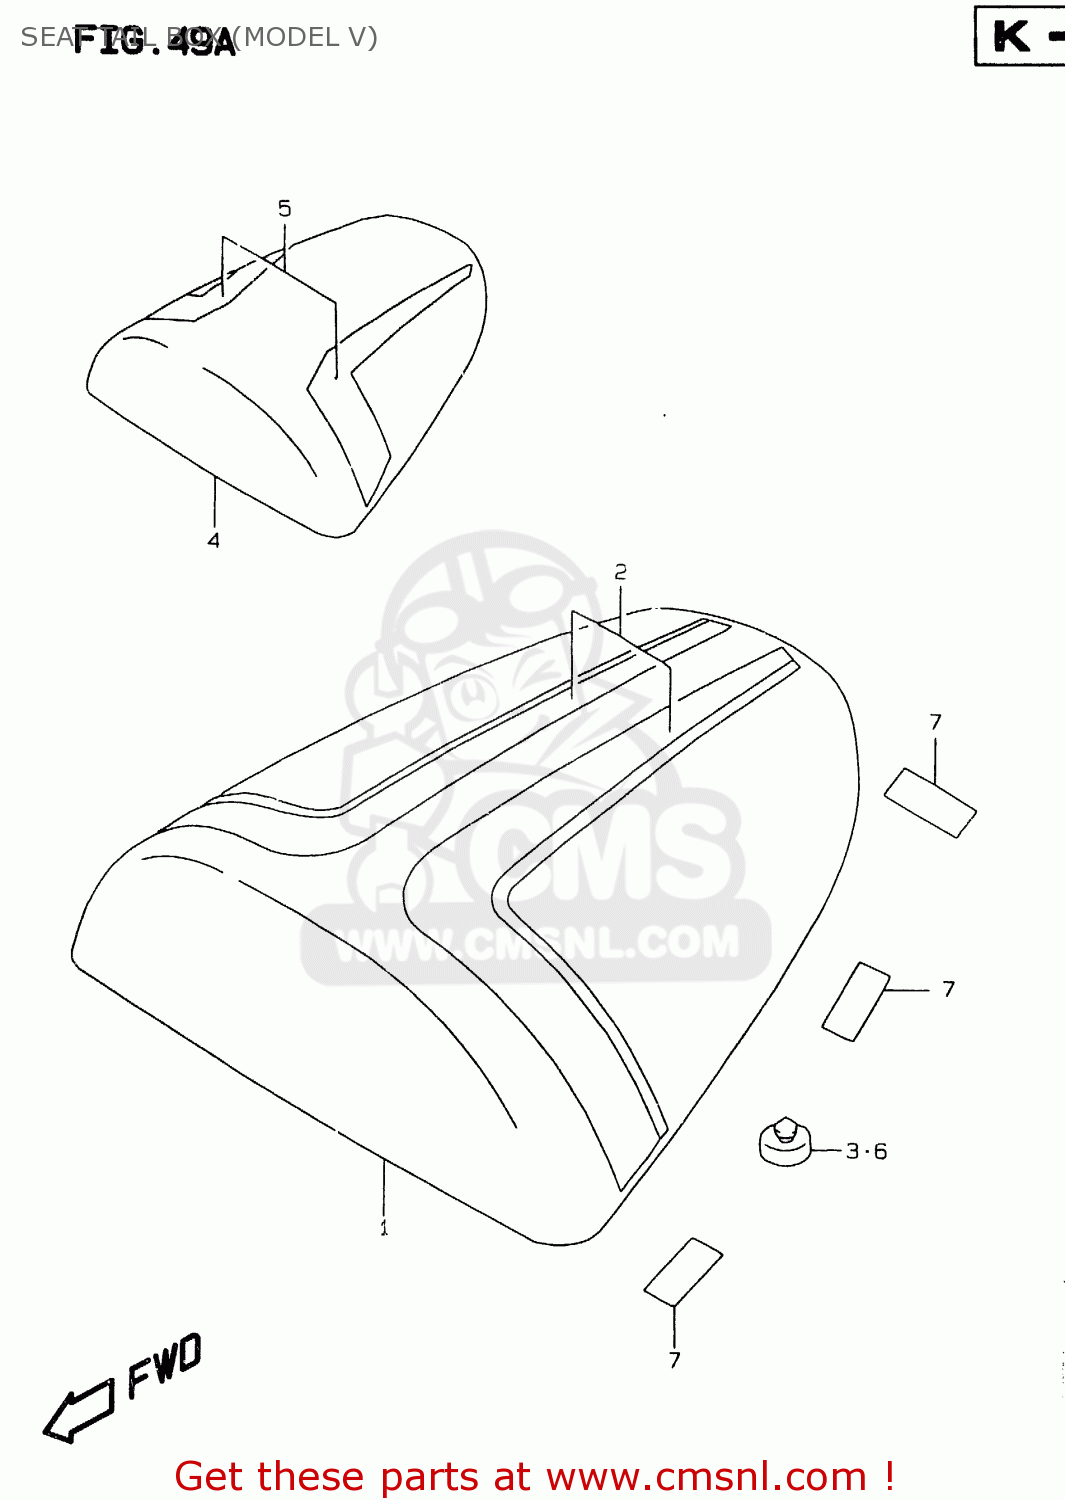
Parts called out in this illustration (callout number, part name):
1	BOX ASSY,SEAT TAIL(WHITE)
2	TAPE SET,BOX SEAT TAIL
3	CUSHION(11.5X22X20)
4	BOX ASSY,SEAT TAIL(ORANGE)
5	TAPE SET,BOX SEAT TAIL
6	CUSHION(11.5X22X20)
7	PROTECTOR SET,SEAT TAIL BOX
